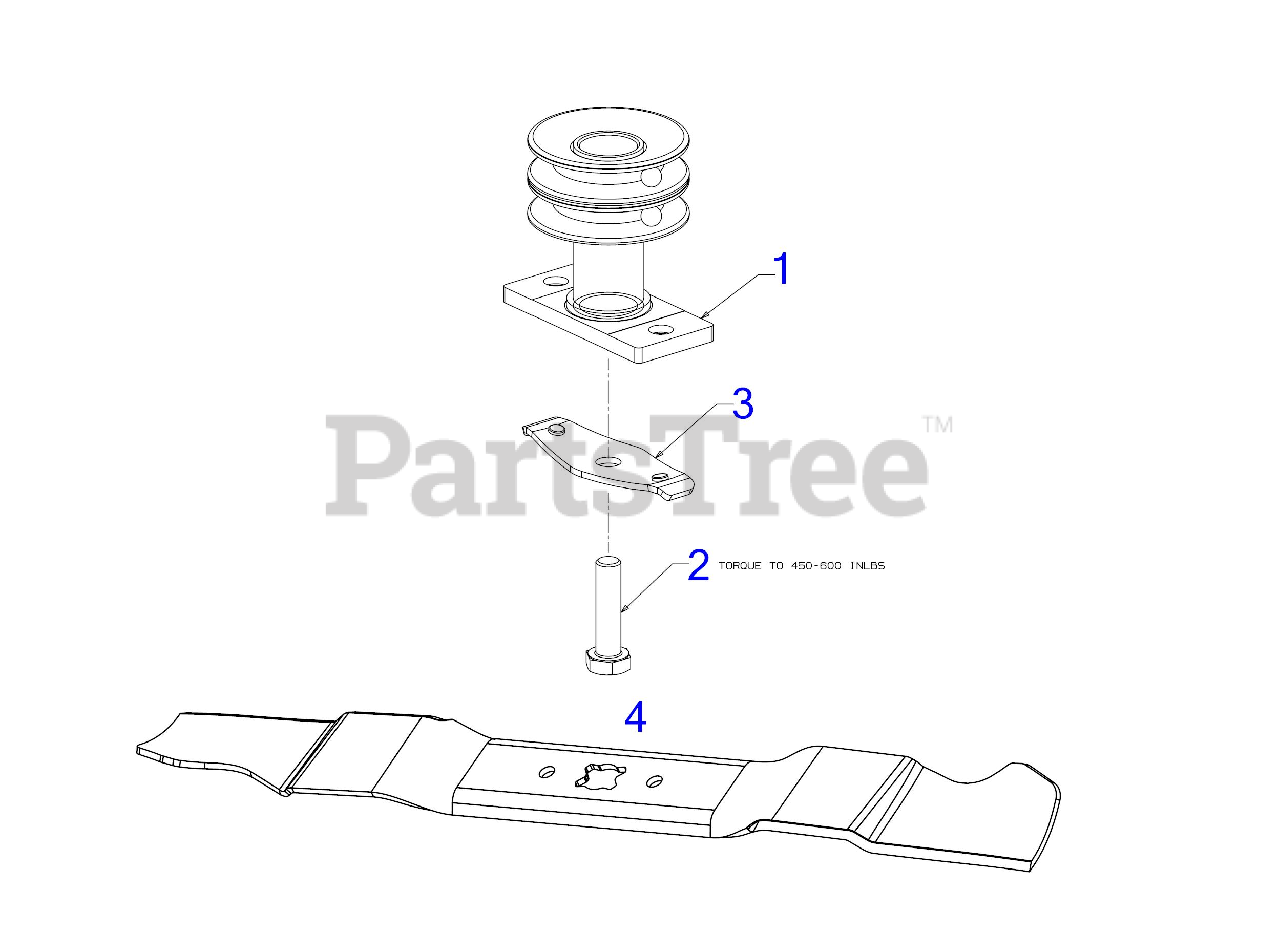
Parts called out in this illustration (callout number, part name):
1	BLADE ADAPTER
2	SCREW 3/8-24 x 1.50 GR8
3	BLADE BELL SUPPORT
4	21" BLADE (MULCH)
